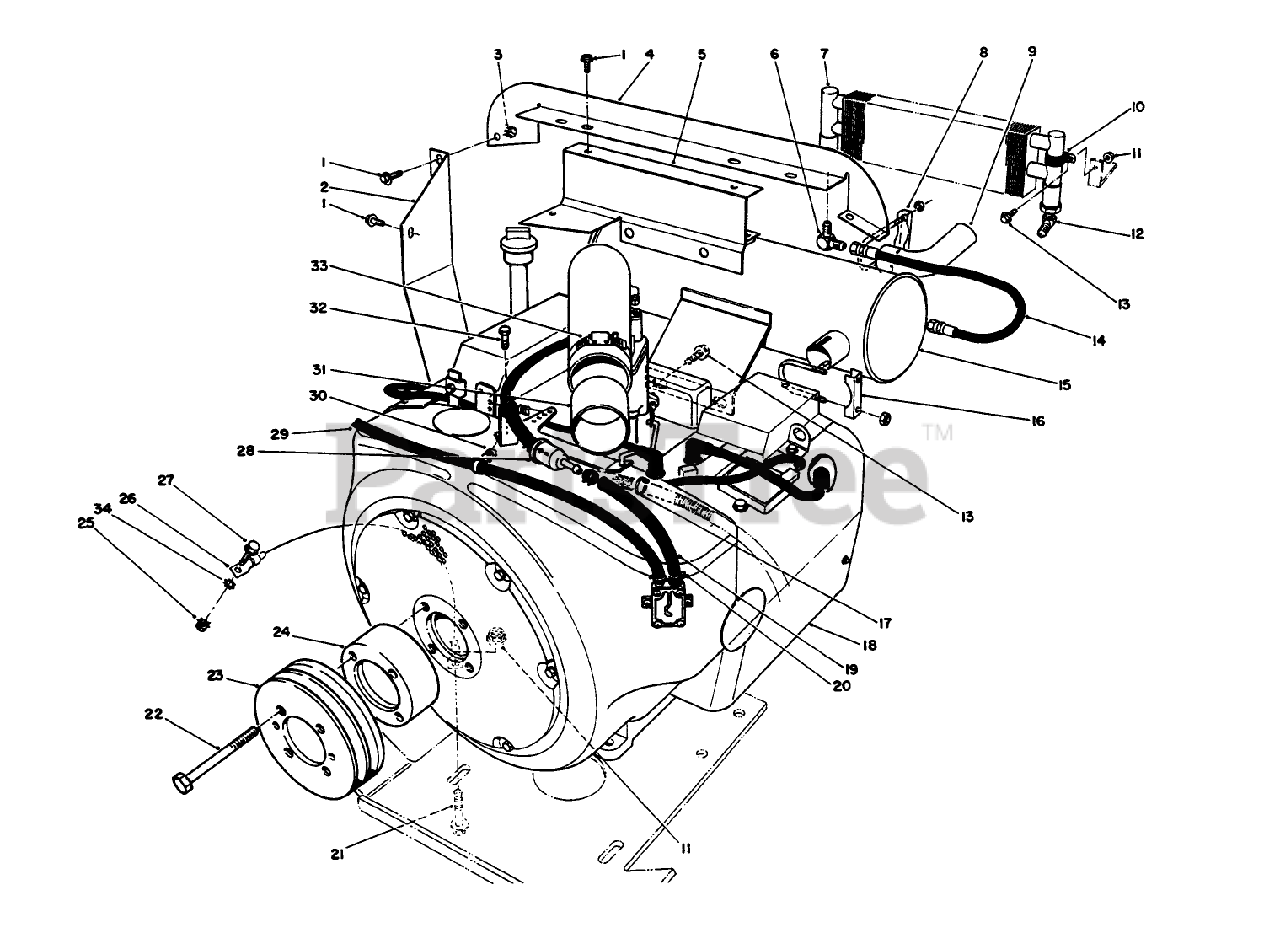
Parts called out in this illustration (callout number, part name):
1	SCREW-HHF
2	Shield-Heat
3	NUT-LOCK, NI
4	Shroud-Engine
5	Bracket-Shield Support
6	90DEG JIC FITTING
7	OIL COOLER
8	CLAMP
9	EXTENSION
10	CLAMP-R
11	NUT-HHF, WHIZ
12	ELBOW
13	SCREW-HHF
14	OIL HOSE ASM
15	MUFFLER
16	MUFFLER CLAMP
17	TIE-CABLE
18	Engine (Onan Model No. P220G-I/10808C
19	Hose
20	CLAMP-HOSE
21	SCREW-HHF
22	SCREW
23	Pulley-Engine
24	PULLEY SPACER
25	NUT-KEPS
26	WIRE ASM
27	SCREW-HHF
28	FILTER-FUEL
29	HOSE
30	R CLAMP
31	AIR CLEANER ADAPTER
32	SCREW-HWHTF
33	CLAMP-HOSE
34	WASHER-LOCK/EXT
